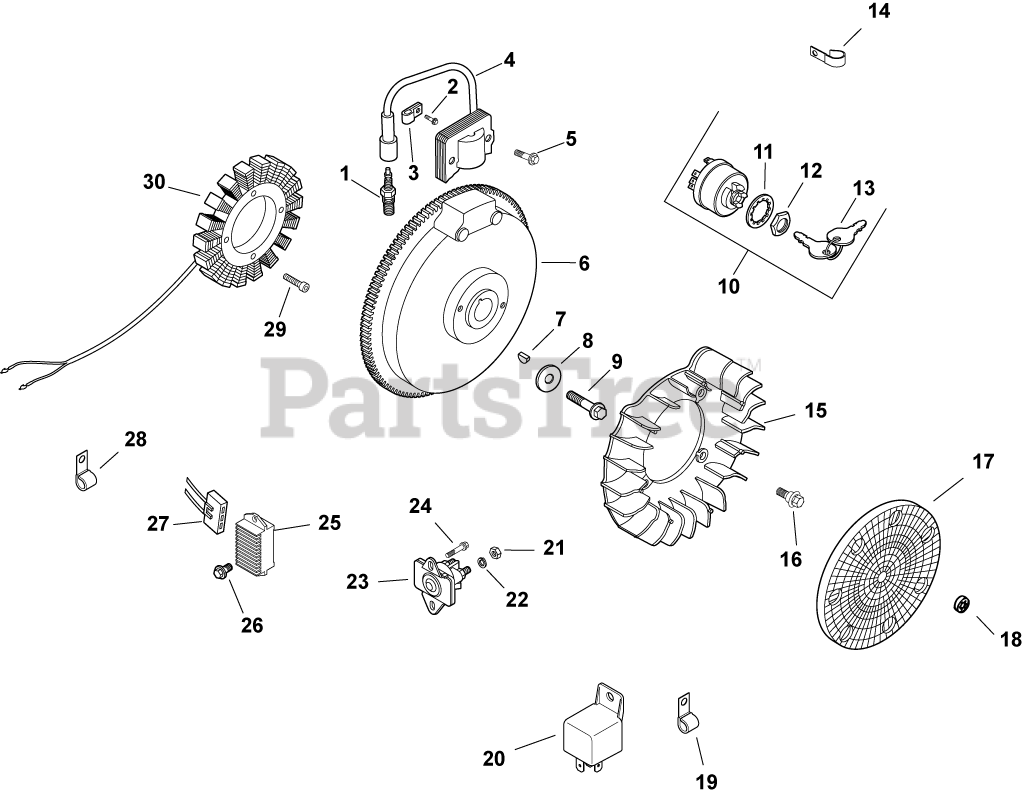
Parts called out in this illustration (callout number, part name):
1	PLUG, SPARK (PRO SERIES)
2	SCREW, FLG THD FRM M5X.8X10
4	MODULE, IGNITION
5	SCREW, FLG THD FRM M5X.8X20-(#25086399S)
6	FLYWHEEL ASSY PAINTED - USE 12 025 74-S
7	KEY, 3/16" X 5/8"
8	WASHER, FLAT 13/32"
9	SCREW, FLG M10X1.5X45 - (#25086361S)
10	SWITCH ASSY, KEY (KM)-USE 25 099 32-S
11	WASHER, INTERNAL TOOTH
12	NUT, KEY SWITCH
13	KEY, SET -USE 48 340 01-S
14	CLIP, CABLE
16	BOLT, SHOULDER
17	SCREEN, GRASS
21	NUT, JAM 1/4-20 GRADE 2
22	WASHER, INT TOOTH LOCK 1/4"
23	SOLENOID - WATERPROOF (KM)-USE 25 435 08
24	SCREW,FLG THD FRM M6X1.0X16-(#25086397S)
25	REG/RECT-15 AMP (KM)-USE 41 403 10-S
26	SCREW, FLG M6X1.0X16
27	CONNECTOR, BODY (KM)-USE 25 155 41-S
28	CLIP, TUBE & WIRING (KM)
29	SCREW, M5X0.8X25 - (#25086402S)
30	KIT, 15 / 20 AMP STATOR
